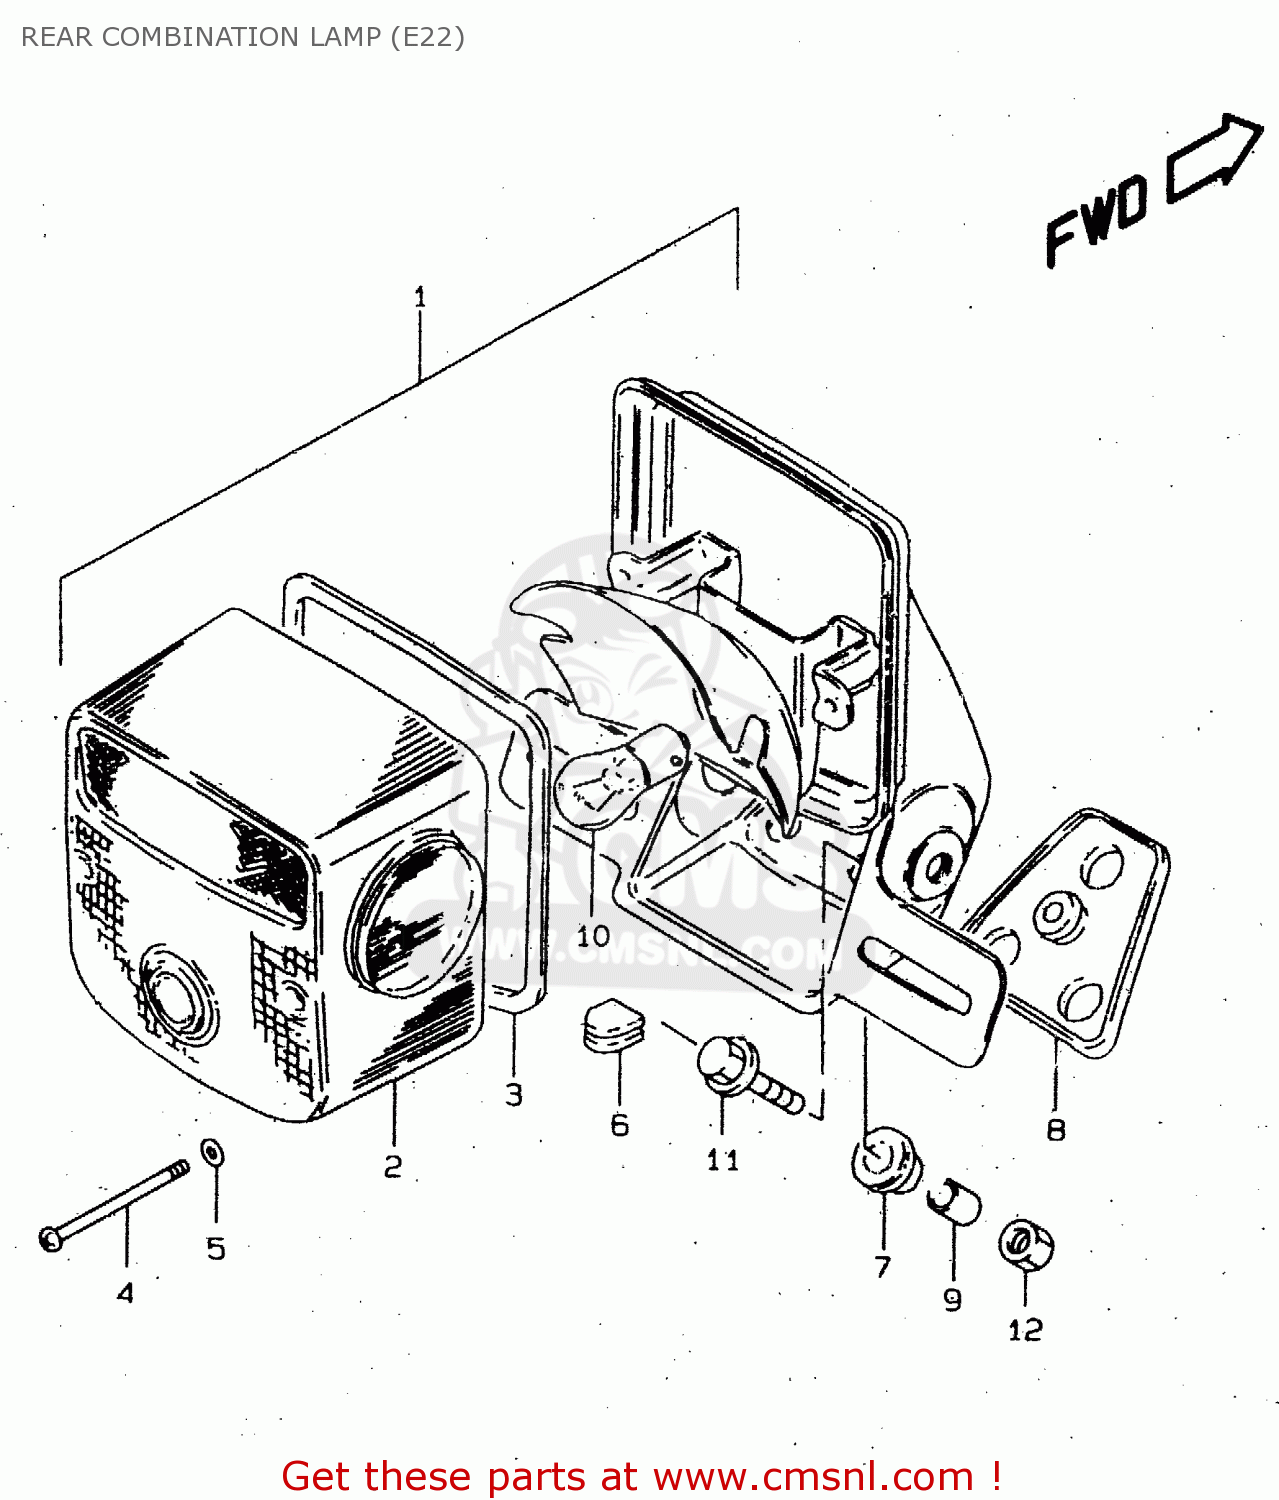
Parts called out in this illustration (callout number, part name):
1	LAMP ASSY,RR COMBINATION
2	LENS
3	GASKET (NAS)
4	SCREW (4X55)
5	GASKET (NAS)
6	GROMMET,REAR COMBINATION LAMP
7	CUSHION
8	CUSHION
9	SPACER
10	BULB(12V21/5W)
11	BOLT(6X20)
12	NUT 6MM
